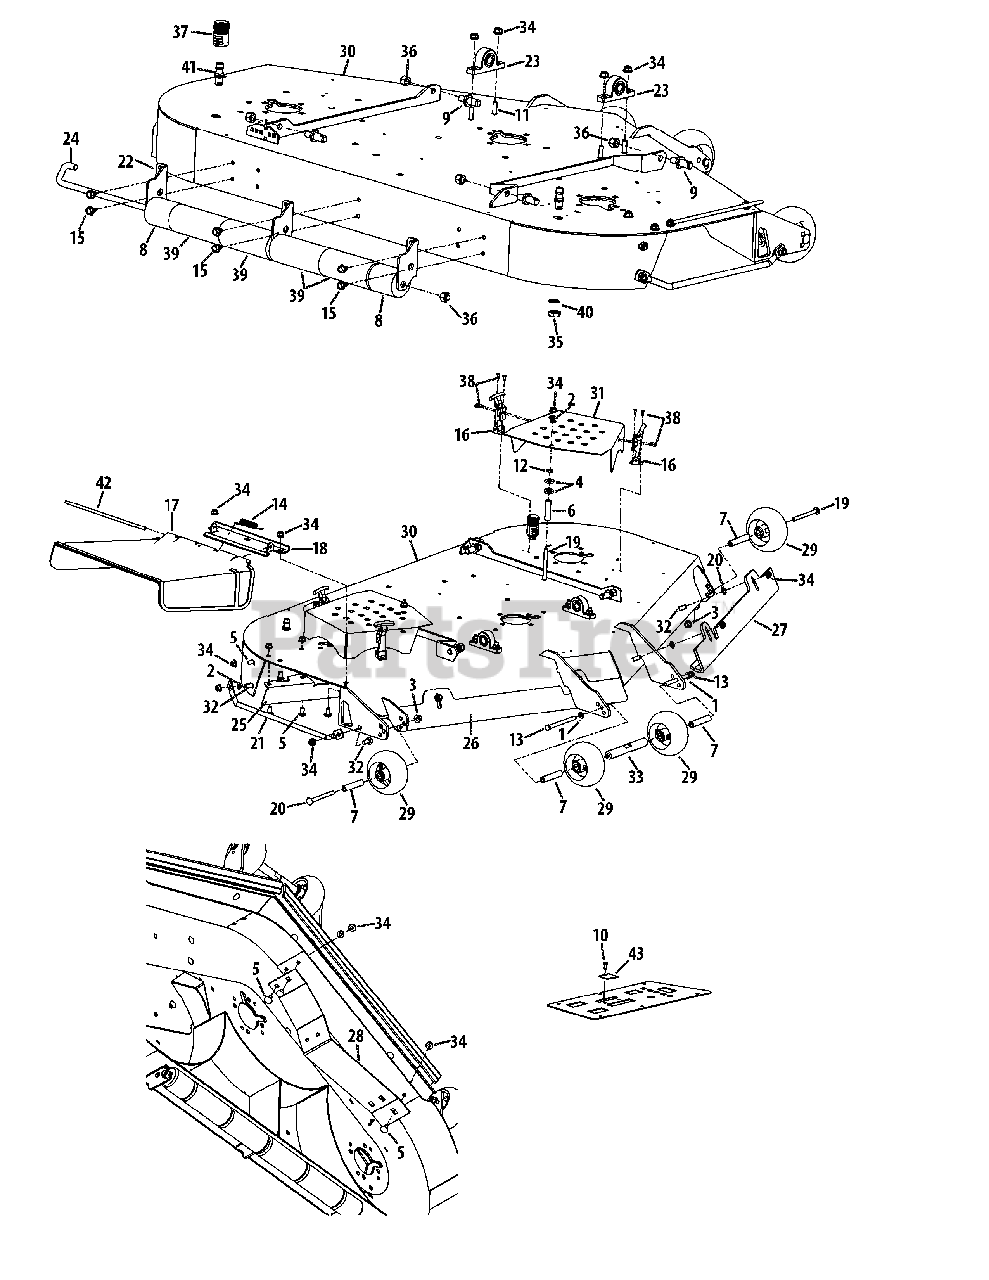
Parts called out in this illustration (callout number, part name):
1	Lock Washer, .375 x .680 x .100
2	Washer, .406 x .813 x .063
3	Flange Counter Lock Nut, 3/8-16
4	Washer, .390 x 1.00 x .180
5	Carriage Bolt, 3/8-16 x .75
6	Spacer, .400 x .560 x 2.45
7	Spacer, .390 x .620 x 3.04
8	Grass Catcher Frame Roller
9	Pin, 5/8 x 1.20
10	Flange Screw, #10-24 x .500
11	Carriage Bolt, 3/8-16 x 1.25
12	Jam Nut, 3/8-16
13	Hex Screw, 3/8-16 x 4.50
14	Torsion Spring
15	Flange Screw, 3/8-16 x .500
16	T-Handle Draw Latch
17	Chute Deflector
18	Chute Deflector Bracket
19	Carriage Bolt, 3/8-16 x 4.00
20	Push Nut, .335 x .780 x .015
21	Finger Guard
22	Right Roller Mount Bracket
23	Steel Pillow Bearing
26	RH Front Adjustable Skirt
27	LH Front Adjustable Skirt
28	Adjustable Baffle
30	Deck Assembly
32	Carriage Bolt, 3/8-16 x 1.00
33	Ball Wheel Frount Mount Shaft
34	Flange Lock Nut, 3/8-16
35	Hex Nut, M16-1.5
36	Hex Lock Nut, 1/2-13
37	Water Nozzle Adapter
38	Rivet, 3/16
39	Front roller
40	Lock Washer, 17 x 23.8 x 1.95
41	Water Deck Nozzle
42	Chute Deflector Rod
43	Throttle Control Bracket
